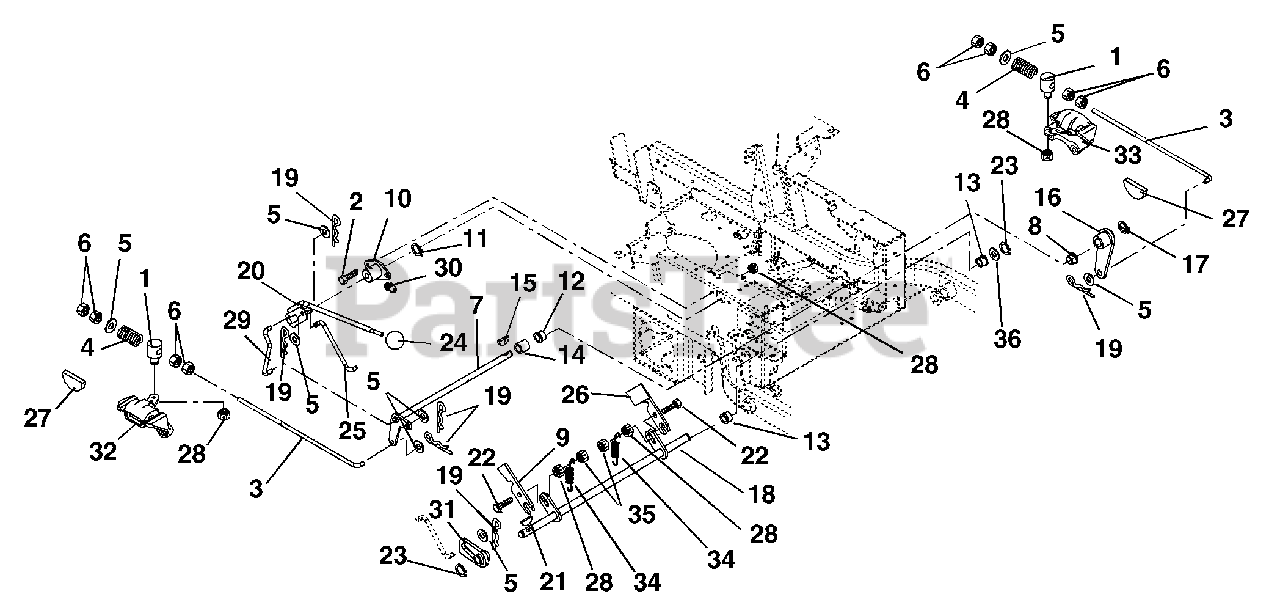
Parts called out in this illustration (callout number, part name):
1	PIN, PIVOT/TRUNNION
2	@BLT-HEX .31-18X.75 GR5 YWZC
3	ROD - BRAKE 12 INCH
4	SG-COMP .142 X .710 X 2.00
5	@WSHR-FL-STL.406X.812X.065 YWZ
6	@NUT-HEX .38-16 YWZC
7	WMT, BRAKE CROSS SHAFT
8	BSHG-FLG .630X1.000X.625 NY
9	SLIDE, INTERLOCKING BRAKE
10	BUSHING, FLANGED (WITH HOLE)
11	RG-RTNG-EXT .625X.050
12	BSHG-FLG .762X1.0X.580X1.48 NY
13	BSHG-FLG.500X.750X.750X1.000BR
14	BSHG-SLV .750X1.000X.750
15	KEY-WDRF .19X.75 HRD #9
16	WMT, BRAKE ARM
17	RG-RTNG-EXT .625X.050
18	WMT, MECHANICAL BRAKE
19	PIN-HAIR, ENDRIES #25 YWZC
20	WMT, BRAKE ACTUATING
21	KEY-WDRF .13X.63 HRD#5
22	@BLT-HEX .31-18X1.25 GR5 YWZC
23	RG-RTNG-EXT .500X.050 (SNAP)
24	KNOB-STEERING LOCK
25	LINKAGE, BRAKE ACTUATING
26	INTERLOCK, SAFETY SWITCH
27	PAD SET, DISK BRAKE
28	@NUT-LK-TOP-FLG .31-18 YWZC
29	LINKAGE, BRAKE ACTUATING
30	FTG-LUBE .25-28X.256 YWZC
31	WMT, PARKING BRAKE HUB
32	BRAKE, RH CALIPER
33	BRAKE, LH CALIPER
34	SG-TENS .061 X .50 X 3.0 WLD 4
35	@NUT-LK-CTR .31-18 YWZC
36	WSHR-FL-STL .505X1.00X.062YWZC
